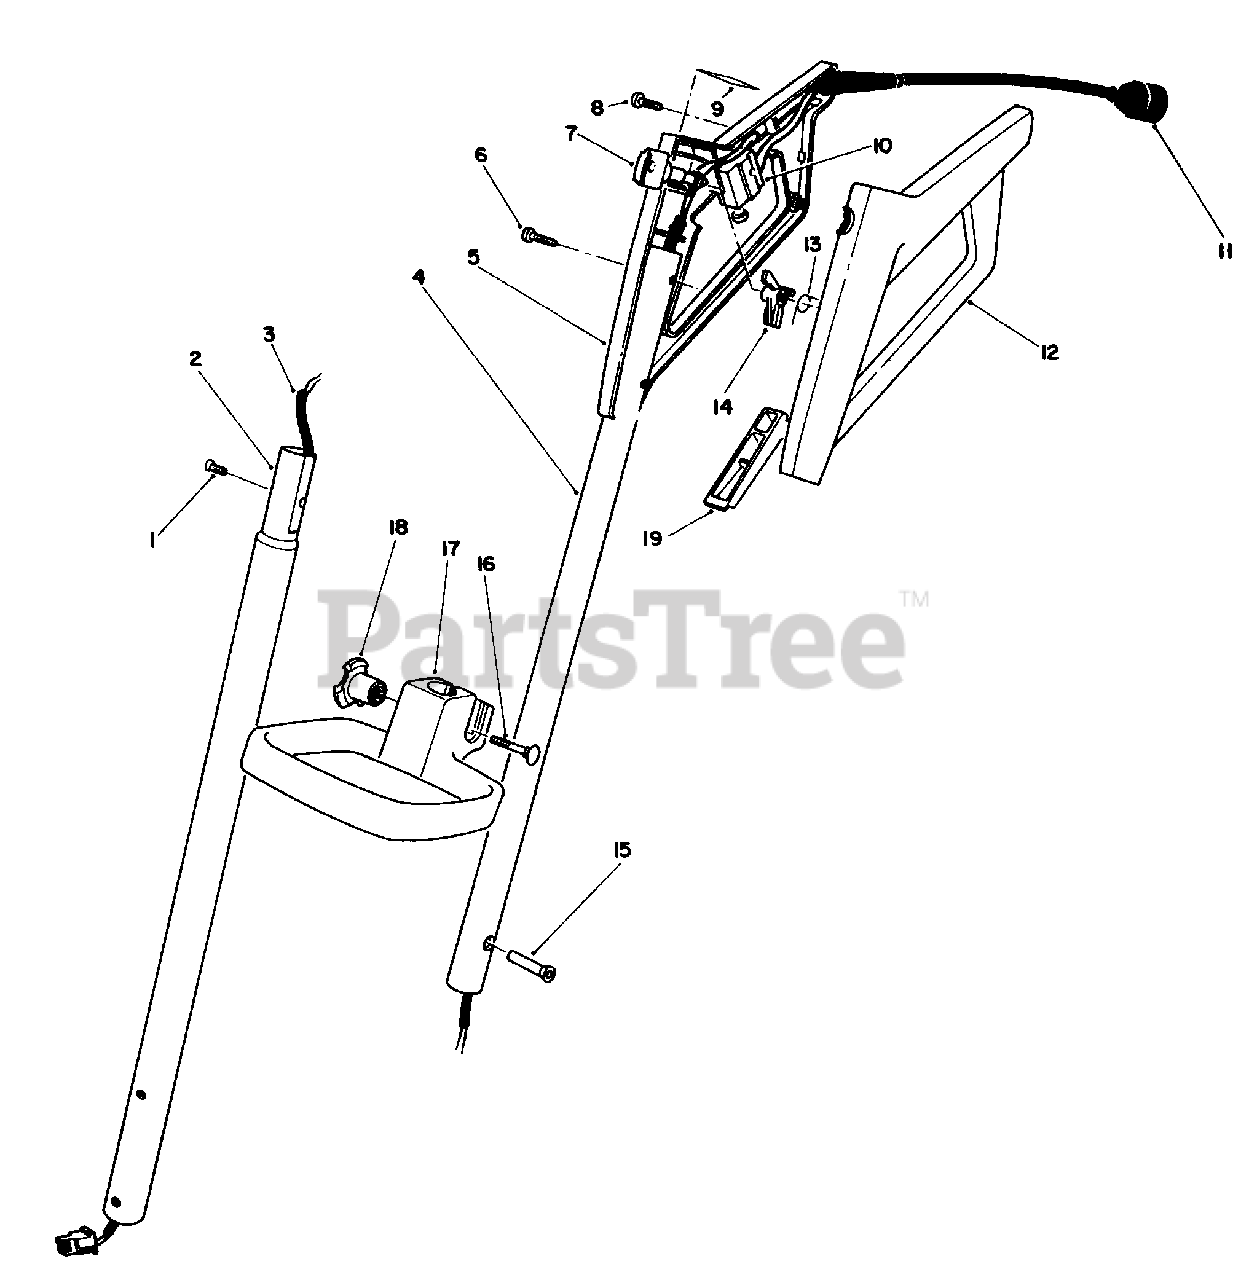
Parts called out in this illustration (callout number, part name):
1	Screw-Flat Head
2	Tube-Lower Handle
3	Wire Harness
4	Tube-Upper Handle
5	Grip-Control R.H.
6	Screw-Pan Hd.
8	Screw-Pan Hd.
9	Decal-Control Grip
11	Cord-Supply
12	Grip-Control L.H.
15	Nut-Counterksunk
16	Bolt-Carriage
17	Handle-Adjustable
18	Knob
19	Switch Bar
